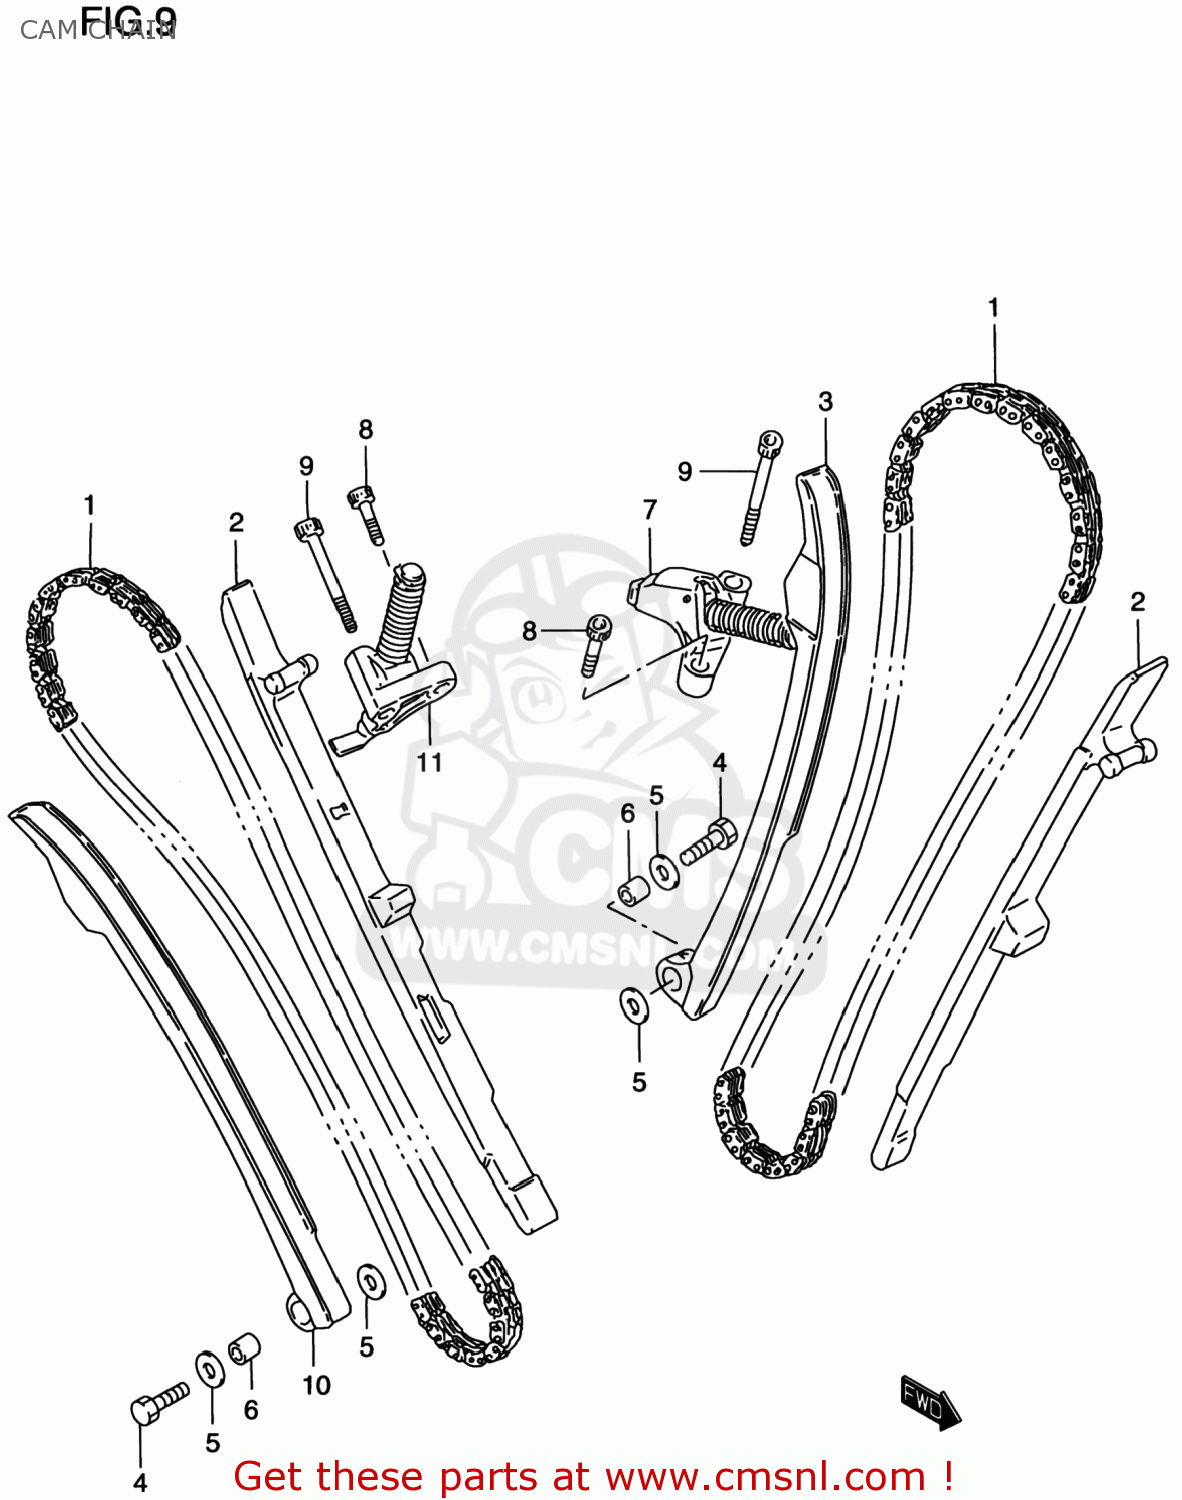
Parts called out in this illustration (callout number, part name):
1	CHAIN COMP,CAMSHAFT DRIVE
2	GUIDE,CAM CHAIN
3	TENSIONER,FR CAM CHAIN
4	BOLT(6X26)
5	WASHER
6	SPACER(6X11X11)
7	ADJUSTER ASSEMBLY,FRONT TENSIONER
8	BOLT,CRKCASE,R
9	BOLT
10	TENSIONER,RR CAM CHAIN
11	ADJUSTER ASSEMBLY,REAR TENSIONER
